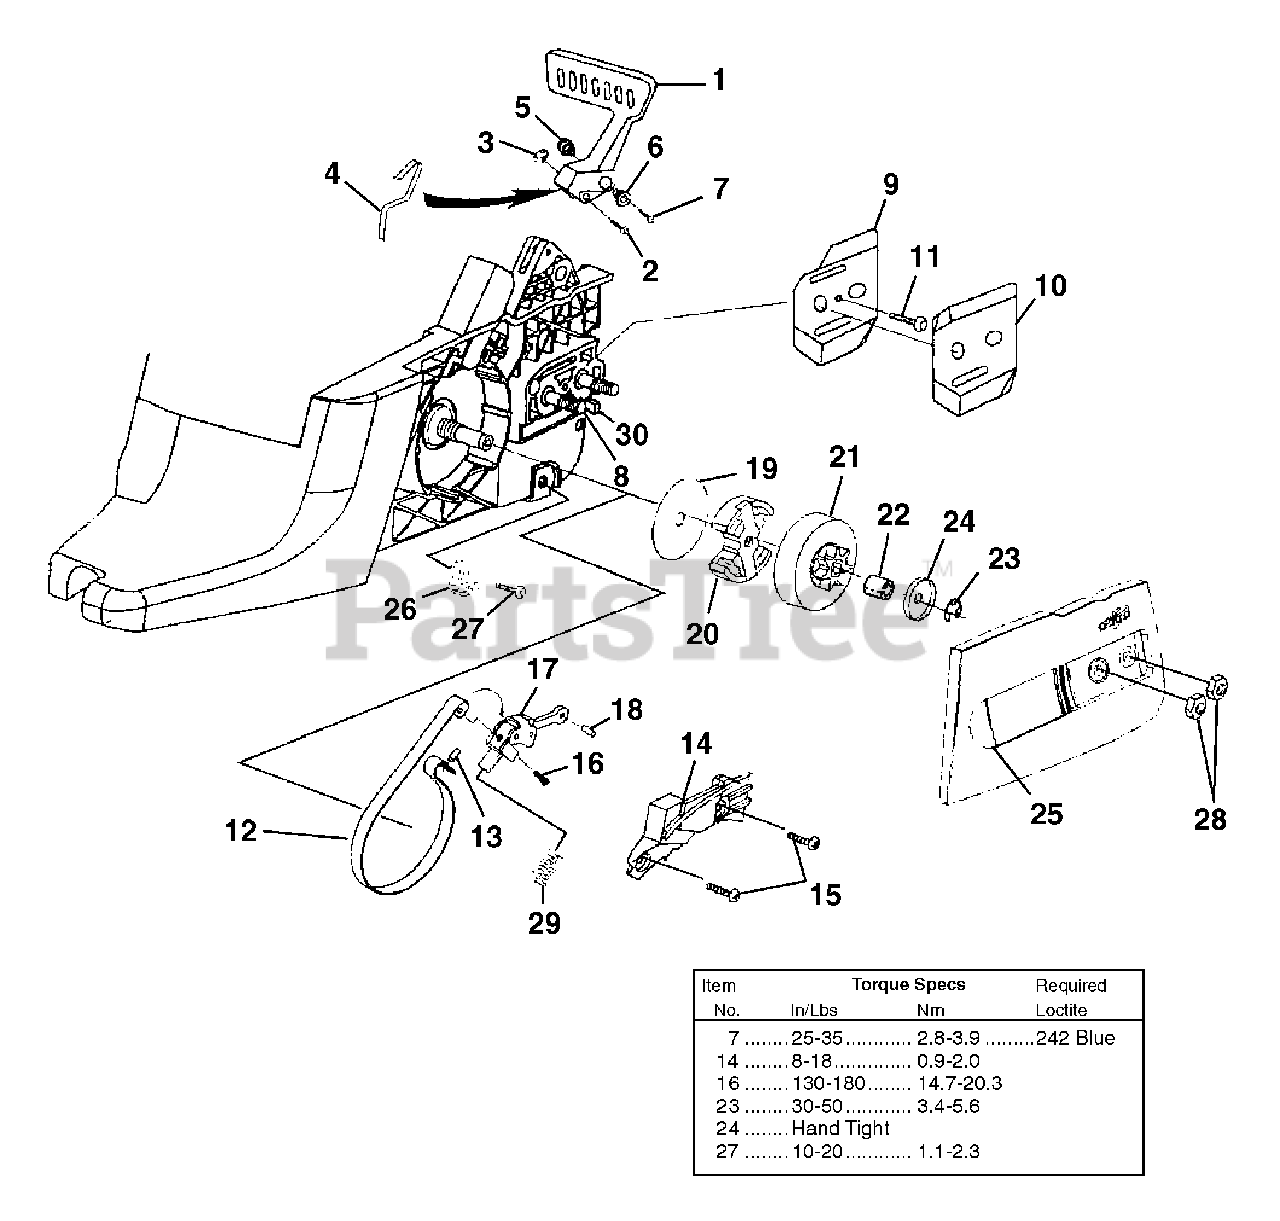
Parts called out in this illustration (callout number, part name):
1	Hand Guard Kit
2	Hand Guard Actuating Pin
3	Retaining Ring
4	Spring, Handguard
5	Pivot, L.H.
6	Pivot, R.H.
7	Screw, Hex Socket Hd. (8-32 x 5/8")
8	Guide Bar Bolt
9	Plate, Guide Bar
10	Plate, Guide Bar
11	Screw, Thread Form (6-19 x 1/2")
12	Chain Brake Band Kit
13	Pin, Roll
14	Cover, Chain Brake
15	Screw, Pan Hd. (6-19 x 1/2")
16	Screw, Pan Hd. (8-16 x .320)
17	Chain Brake Link
18	Pin, Roll
19	Thrust Washer
20	Clutch & Hardware
21	Sprocket, Drum (.325 Pitch)
22	Bearing, Needle
23	Ring, Retaining
24	Washer, Cupped
25	Drive Case Cover
26	Chain Catcher
27	Screw, Thread Form (10-24 x 1/2")
28	Nut, Hex
29	Spring, Compression
30	Adjusting Pin Assembly
